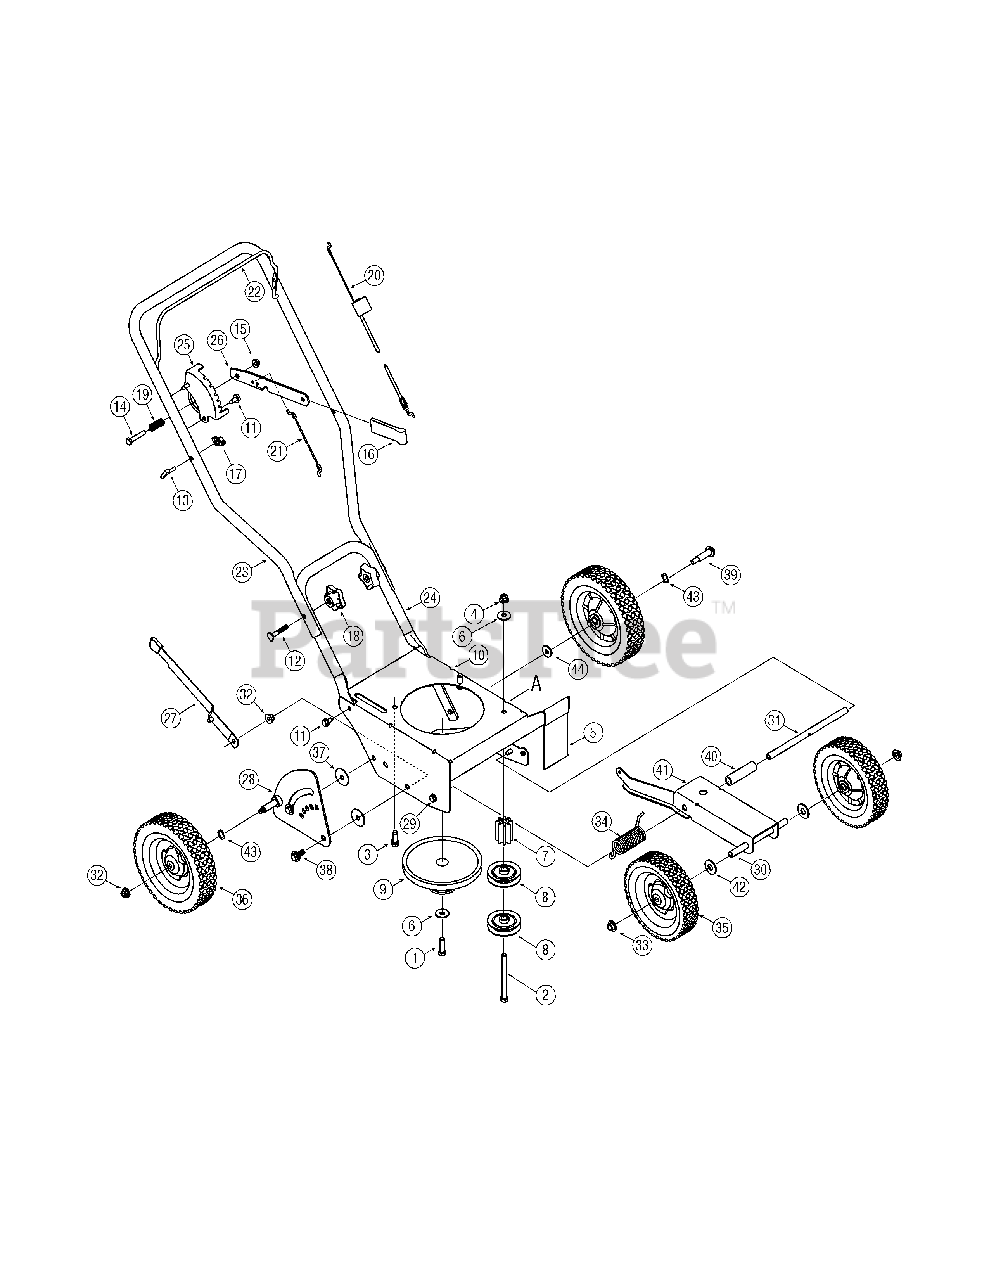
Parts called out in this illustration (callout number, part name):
1	Screw 3/8-24
2	Screw 3/8-16
3	Screw, 3/8-16
4	Flange Lock Nut, 3/8-16
5	Debris Guard
6	Bell Washer,.396 x 1.140
7	Pulley Mount Spacer
8	Flat Idler Pulley, 2.5 OD
9	Combination Flywheel Pulley
12	Carriage Bolt, 5/16-18
13	Rope Guide (Eye Bolt)
14	Hex Screw, 5/16-18
15	Lock Flange Nut, 5/16-18
17	Wing Nut
18	Hand Knob
19	Compression Spring
20	Control Cable (Briggs & Stratton)
21	Wheel Adjustment Cable
24	Threaded Frame Spacer
27	Curb Height Adjustment
28	Curb Height Adjuster Plate
29	Hex Screw 5/16-18
30	Axle Shaft .50x6.65
31	Frame Spacer .50x9.25
32	Flange Nut 3/8-16
33	Push Cap 1/2" rod
34	Torsion Spring
35	Wheel 7x1.8
36	Wheel 8x1.8
37	Flat Washer, .385 x 1.5 x .075
38	Shoulder Screw, 3/8-16
39	Shoulder Screw, 3/8-16
40	Spacer
42	Flat Washer 1/2 x 1.25 x .10
43	Wave Washer .531 x .781 x .013
44	Flat Washer .385 x 1.0 x .135
